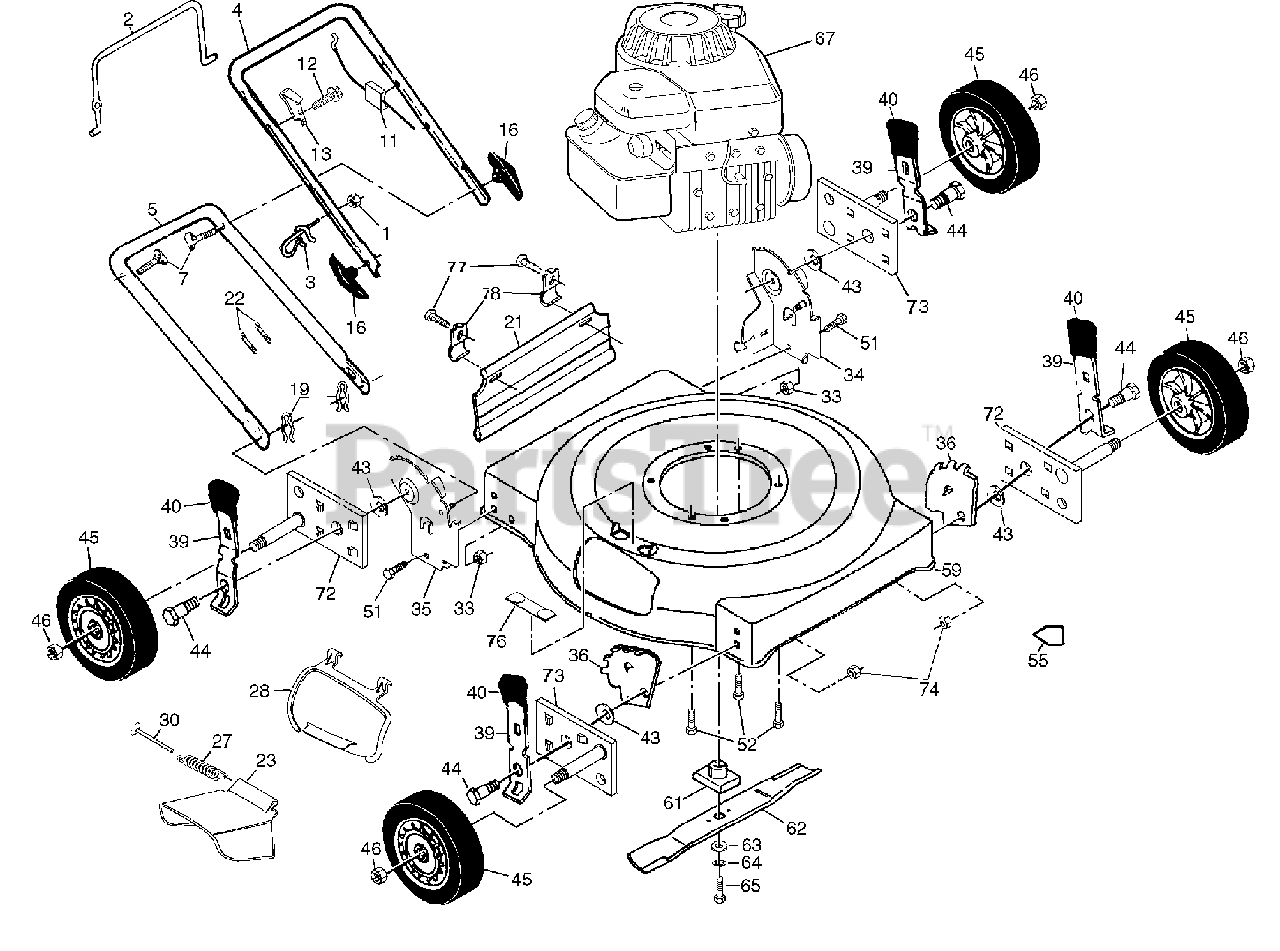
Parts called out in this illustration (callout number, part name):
1	Locknut 1/4-20
2	Control Bar
3	Rope Guide
4	Upper Handle
5	Lower Handle
7	Handle Bolt 5/16-18
11	Engine Zone Control Cable
12	Hex Washer Head Screw #10-24 x 1/2
13	Up-Stop Bracket
16	Knob
19	Hairpin Cotter
21	Rear Deflector
22	Wire Tie
23	Discharge Guard
27	Torsion Spring
28	Mulcher Plate
30	Hinge Rod
33	Nut, Hex, Flangelock 5/16 - 18
34	Wheel Bracket Support, Left
35	Wheel Bracket Support, Right
36	Wheel Bracket Adjuster
39	Selector Spring
40	Selector Knob
43	Washer
44	Shoulder Bolt 5/16-18 x .33
45	Wheel Assembly
46	Locknut 1/16-18
51	Screw, Hex Head, Serrated, Type TT 1/4 x 20
52	Screw, Hex Head, Threaded, Rolled 3/8-16 x 1
55	Danger Decal
59	Lawn Mower Housing
61	Blade Adapter
62	22" Blade
63	Hardened Washer
64	Helical Lockwasher 3/8
65	Screw, Hex Head 3/8-24 x 1-3/8 Grade 8
72	Axle Arm Assembly (LF/RR)
73	Axle Arm Assembly (RF/LR)
74	Nut, Hex
76	Clip, Closeout
77	Screw
78	Shoulder Bolt 5/16-18 x .51
78	Operator's Manual, English
78	Operator's Manual, Spanish
78	Repair Parts Manual
78	Grass Catcher
